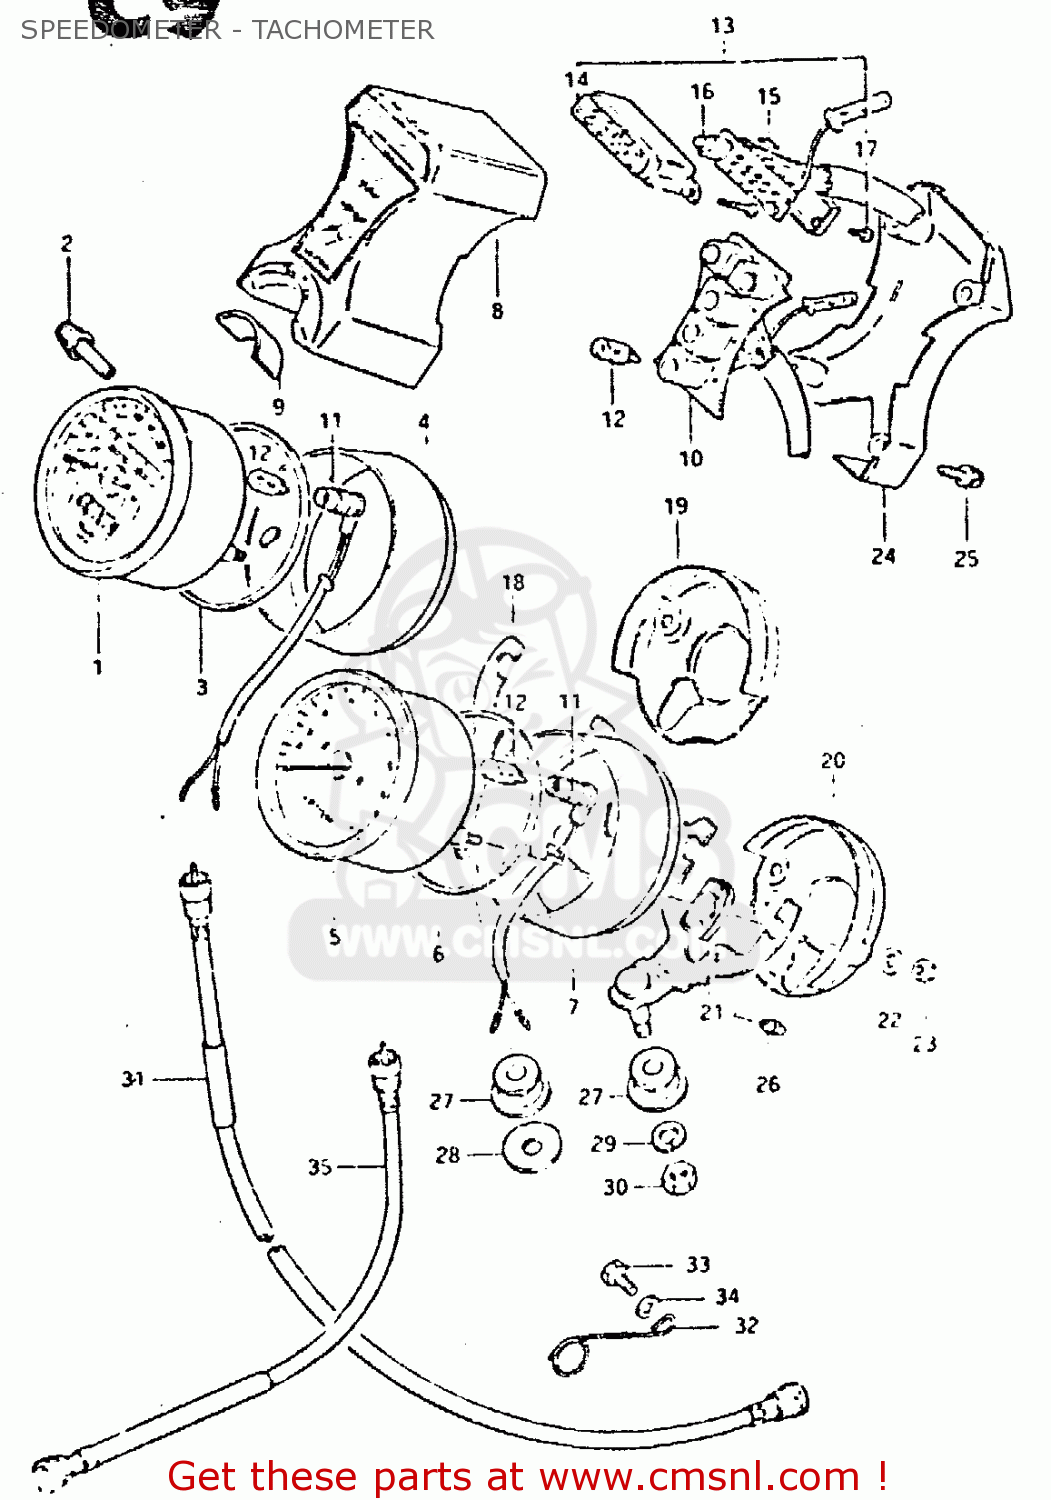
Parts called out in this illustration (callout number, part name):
1	SPEEDOMETER ASSEMBLY
2	KNOB
3	CUSHION
4	COVER,SPEEDOMETER
5	TACH0METER
6	CUSHION
7	COVER,TACHOMETER
8	CASE,PILOT BULB
9	SEAL,IGNITION SWITCH
10	SOCKET
11	SOCKET,METER
12	BULB(12V3.4W,T10)
13	INDICATOR ASSEMBLY,GEAR POSITION
14	CASE,GEAR INDICATOR
15	COVER,LWR
16	BULB(14V1.12W)
17	SCREW,GEAR INDICATOR
18	BRACKET,METER
19	ORNAMENT,SPEEDOMETER
20	COVER,TACHOMETER
21	CUSHION,METER
22	WASHER
23	NUT
24	COVER,PILOT BOX LWR
25	SCREW,PILOT BULB CASE
26	CUSHION
27	CUSHION,METER BRACKET
28	WASHER (8.5X29X1.6)
29	LOCK WASHER
30	NUT
31	CABLE ASSEMBLY,SPEEDOMETER
32	CLAMP,SPEEDOMETER CABLE
33	BOLT, UPPER
34	WASHER
35	CABLE ASSY,TACHOMETER
